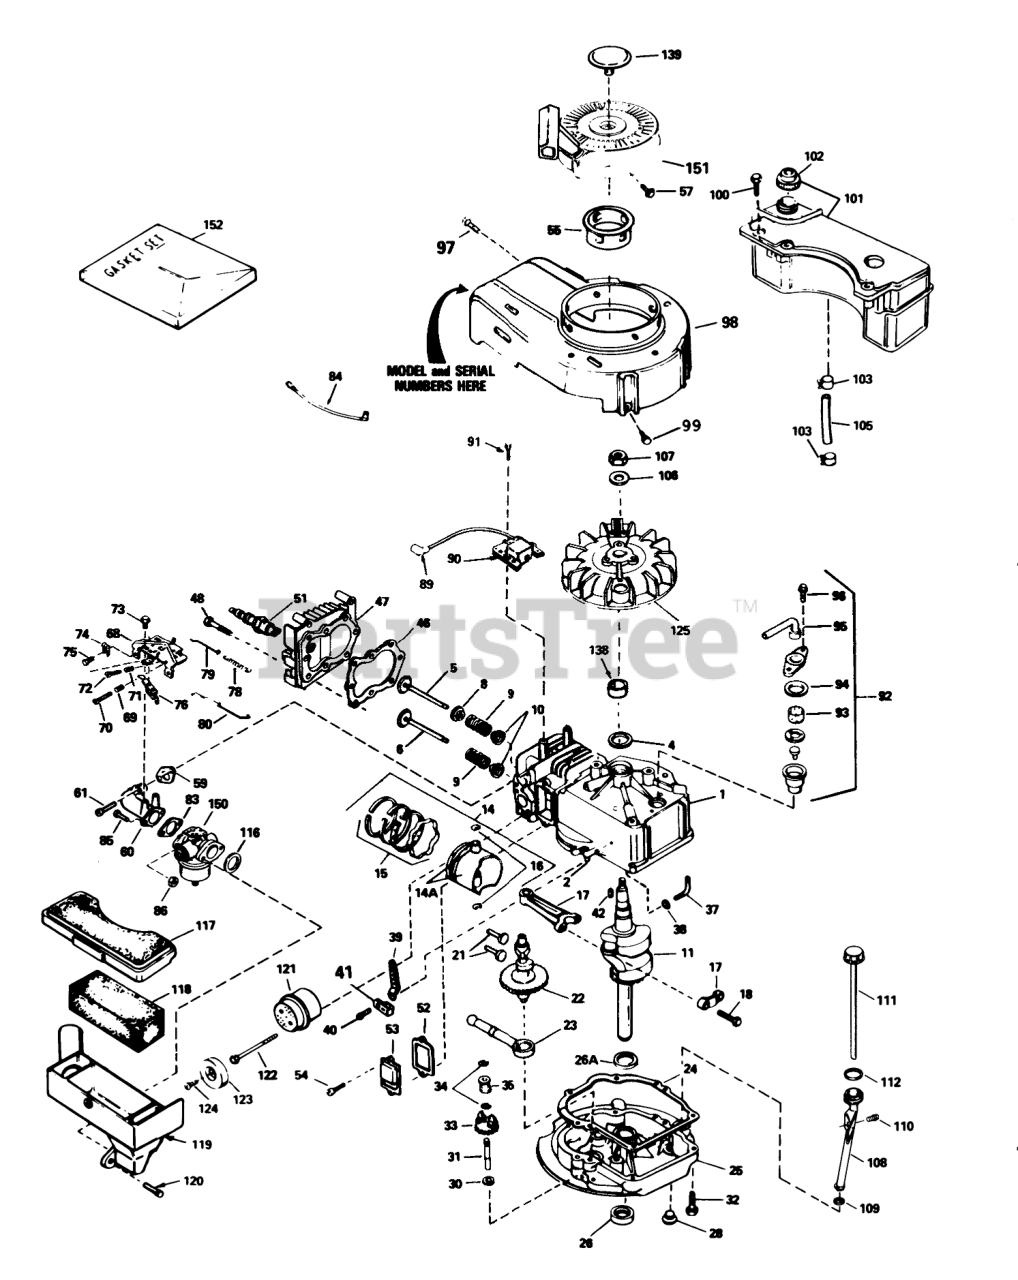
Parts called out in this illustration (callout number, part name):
1	Cylinder Assembly (Incl. Ref. #2 & 4)
2	Pin-Dowel
4	Seal-Oil
5	Valve-Intake (Std.)(Incl. Ref. #10)
5	Valve-Intake (1/32"oversize)(Incl. Ref. #10)
6	Valve-Exhaust (Std.)(Incl. Ref. #10)
6	Valve-Exhaust (1/32"oversize)(Incl. Ref. #10)
8	Seal Assy., Intake
9	Spring-Valve
10	Cap-Valve, Spring
11	Crankshaft
14	Piston-Pin & Ring Assy. (Std.)(Incl. Ref. #14A, 15 & 16)
14	Piston-Pin & Ring Assembly (.010 oversize)(Incl. Ref. #14A, 15 & 16)
14	Piston-Pin & Ring Assembly (.020 oversize)(Incl. Ref. #14A, 15 & 16)
14A	Piston & Pin Assembly (Std.)(Incl. Ref. #16)
14A	Piston & Pin Assembly (.010 oversize)(Incl. Ref. #16)
14A	Piston & Pin ASM(.020" OS)(Incl. 43)
15	Ring Set-Piston (Std.)
15	Ring Set, Piston(.0100versize)
15	Ring Set (.020" OS)
16	Ring-Retaining, Piston Pin
17	Rod Assembly-Connecting (Incl. Ref. #18)
18	Bolt-Rod, Connecting
21	Lifter-Valve
22	Camshaft(Mech.Comp. Release)
23	Oil Pump ASM
24	Gasket
25	Flange Assembly-Mounting (Incl. Ref. #26, 28 & 31)
26	Seal-Oil
26A	Washer-Thrust
28	Plug Oil Drain
30	Washer-Flat
31	Shaft-Governor
32	Screw (1/4-20 x 1-1/4)
33	Gear Assembly-Governor (Incl. Ref. #30)
34	Ring-Retaining
35	Spool-Governor
37	Rod-Governor (Incl. Ref. #38)
38	Washer-Flat
39	Governor Lever
40	Screw
41	Clamp-Lever, Governor
42	Key-Flywheel
46	63573 GIL 42 SNWTHW
47	Head-Cylinder
48	Screw (5/16-18x1-1/2)
51	Spark Plug-Resistor (R J19 L M)
52	Gasket-Breather
53	Cover-Valve
55	Hub-Starter
57	Screw, Hex Hd.
59	Gasket-Intake
60	Pipe-Intake (Incl. Ref. #59)
61	Screw (1/4-20 x 1)
68	Control Assy.-Remote Speed (Incl. Ref. #69 thru 72)
69	61709/GIL1515A/95-5
70	Screw
71	Spring-Compression
72	Screw
73	Screw (10-24 x 9/16)
74	Conduit
75	Screw (10-32 x 3/8)
76	Terminal
78	Spring Governor
79	2035A67 ADD.ASSEMBL
80	Link-Throttle
84	Wire-Ground
85	Screw (1/4-28 x 7/8)
86	Nut and Lock Washer (1/4-28)
89	Cover-Spark Plug
90	Solid State
91	Screw
92	Breather Assembly (Incl. Ref. #93 thru 96)
93	Element-Breather
94	Gasket-Breather
95	Tube, Breaker
96	Screw (10-24 x 9/16)
97	Screw (10-24 x 9/16)
98	Housing-Blower
99	Screw (1/4-20 x 1/2)
100	Screw (10-32 x 35/64)
101	Tank Assembly-Fuel (Incl. Ref. #102 & 103))
102	Cap-Fuel
103	Clamp-Line, Fuel
105	Line-Fuel
106	Washer-Belleville
107	Nut-Flywheel
108	Oil Fill Tube
110	Screw (10-32 x 1/2)
111	Dipstick
112	55063 SNWTHWR ADD.W
116	Gasket-Cleaner, Air
117	Cover-Air Cleaner
118	Filter-Air Cleaner
119	Body Air cleaner
121	Muffler (Incl. Ref. #122)
123	Cover-Muffler
124	Screw (8-32 x 3/8)
125	Flywheel
139	Plug Starter
150	Carburetor (Inc. Ref. #83)
151	Starter-Rewind
152	Gasket Set (Includes items marked )
